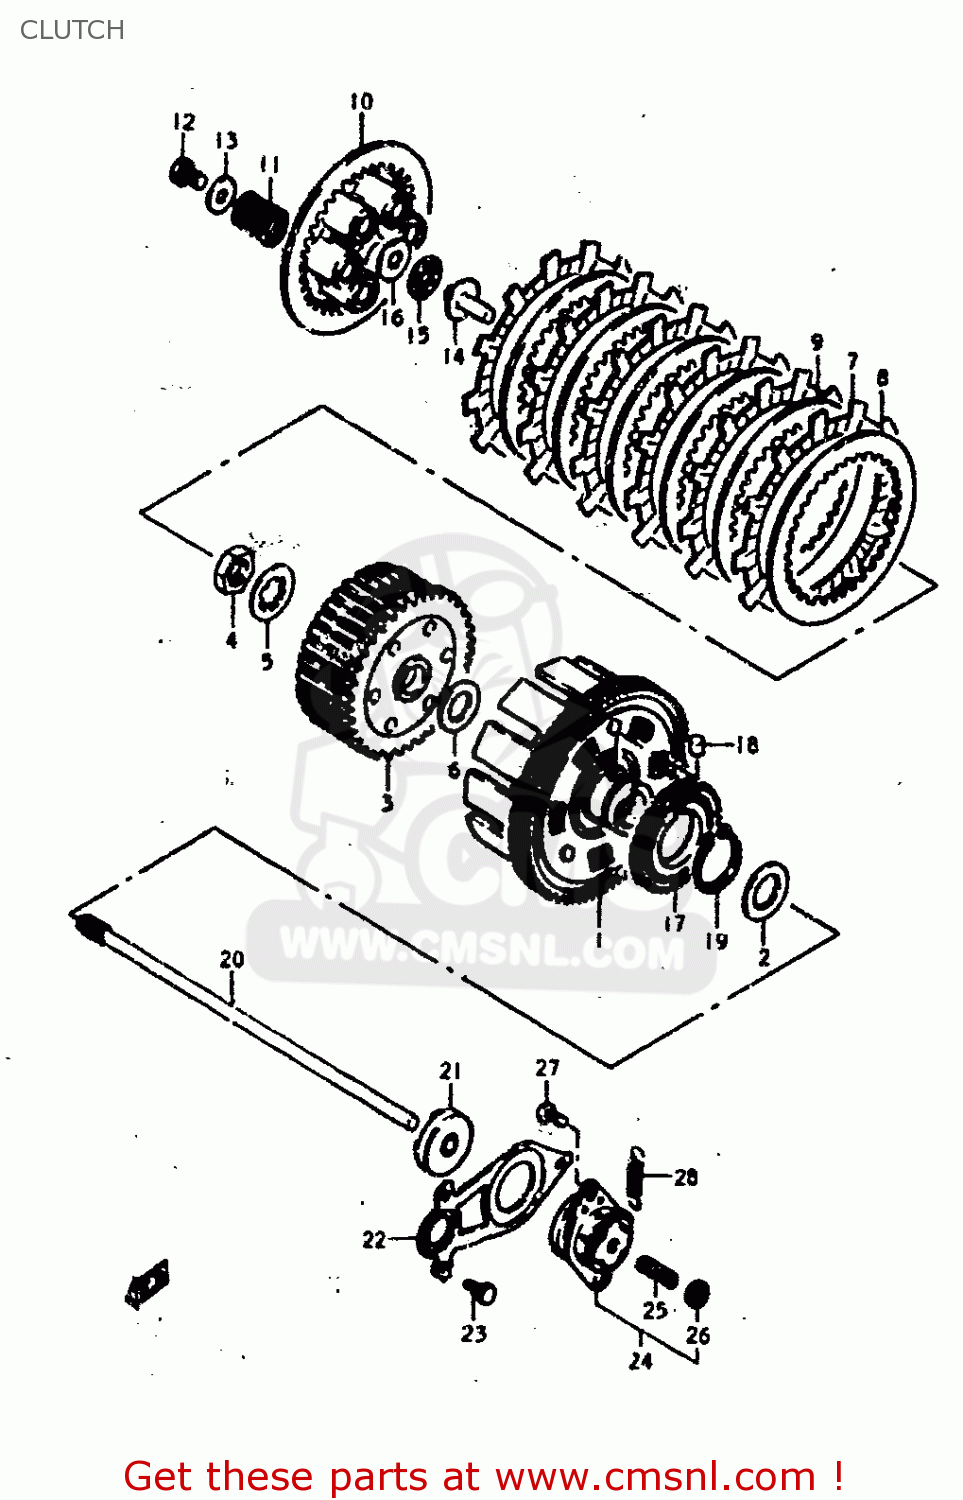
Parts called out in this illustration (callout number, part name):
1	GEAR ASSEMBLY,PRIMARY DRIVE
2	WASHER
3	HUB,CLUTCH SLEEVE
4	NUT (20MM)
5	WASHER,LOCK
6	WASHER(20X38X2)
7	PLATE,CLUTCH DRIVE (NAS)
8	PLATE,CLUTCH DRIVEN(T:2.0) (NAS)
9	PLATE,CLUTCH DRIVEN (NAS)
10	DISC,CLUTCH PRESSURE
11	SPRING
12	BOLT, UPPER
13	WASHER
14	PIECE,CLUTCH PUSH
15	BEARING(15X28X2)
16	WASHER
17	GEAR,OIL PUMP DRIVE
18	PIN(6X6)
19	CIRCLIP
20	ROD,CLUTCH PUSH
21	OIL SEAL
22	RETAINER,CL PUSH ROD OIL SEAL
23	BOLT
24	SCREW ASSEMBLY,CLUTCH RELEASE
25	SCREW
26	NUT 6MM
27	SCREW 6X12
28	SPRING
